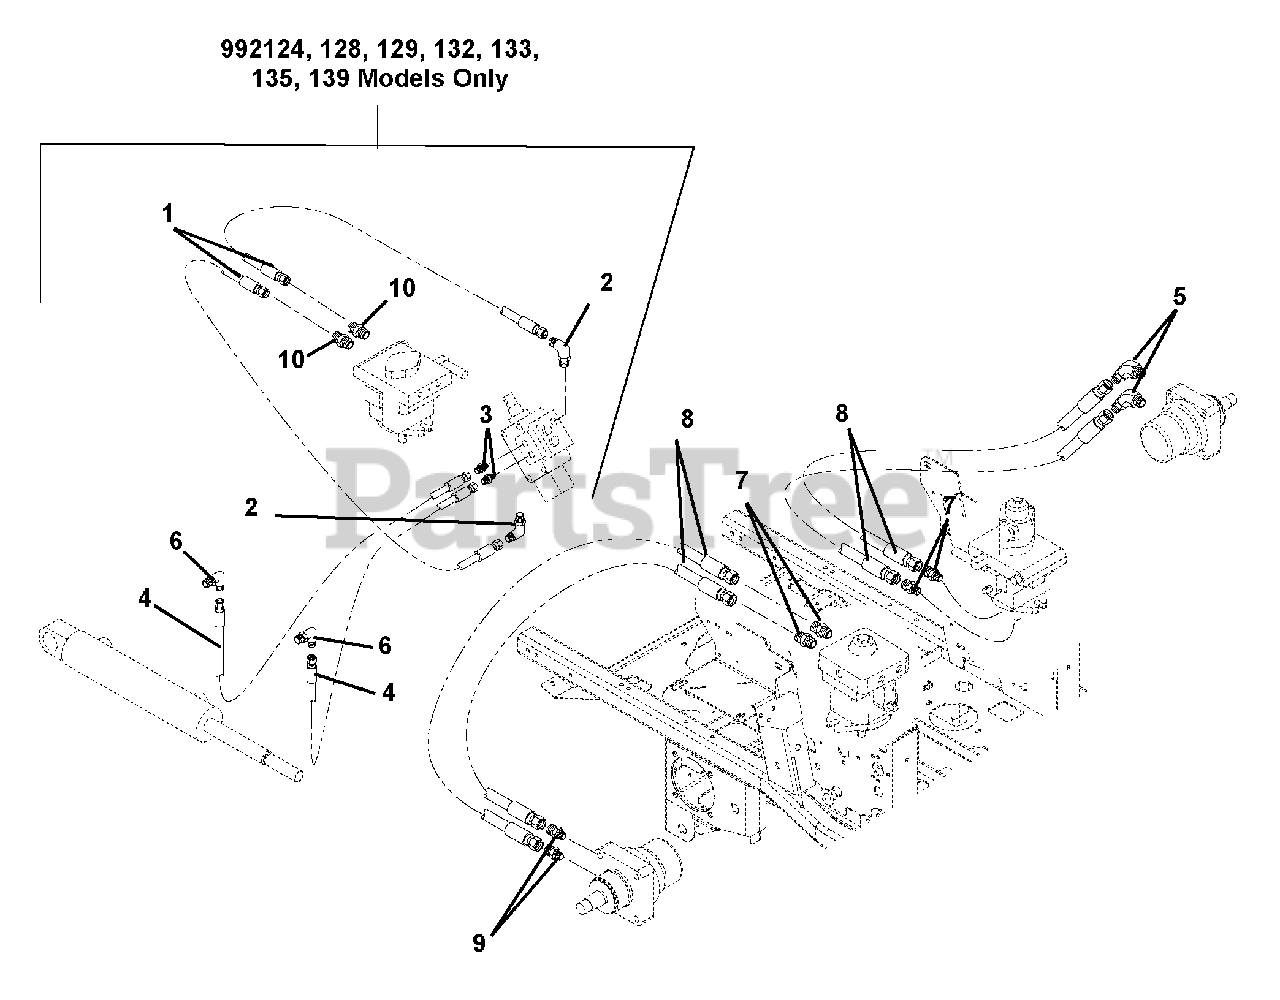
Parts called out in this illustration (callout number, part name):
1	Hose, Hydraulic
2	Hydraulic, Fitting Elbow
3	Adapter (4-6F5OLO)
4	Hose, Hydraulic
5	Fitting, Hydraulic (8-10 V5OLO)
6	Fitting, Hydraulic (4 C5OLO)
7	Adapter, Face Seal 8 x 8 .50 O-Ring
8	Hose, Hydraulic .50
9	Adapter, Hydraulic Steel (M10 O-M8F)
10	Fitting, Hydraulic (4 F5OLO)
